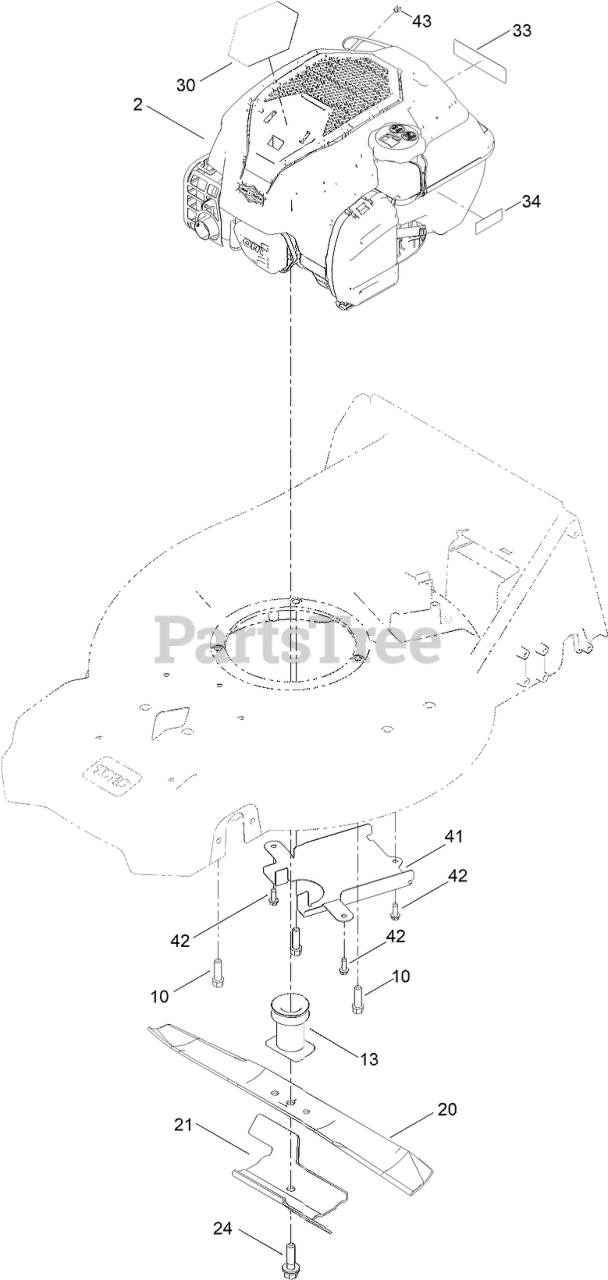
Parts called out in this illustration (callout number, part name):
10	SCREW-TAPTITE
13	DRIVER-BLADE
20	BLADE-21IN, RECYCLING
21	ACCELERATOR-BLADE
24	BOLT-BLADE
30	DECAL-BRIGGS 725 EXI SS
33	DECAL-ARRESTOR, SPARK
34	DECAL-LEVEL, FUEL
41	COVER-BELT, BOTTOM
42	SCREW-HWHTF
43	STOP-ROPE
